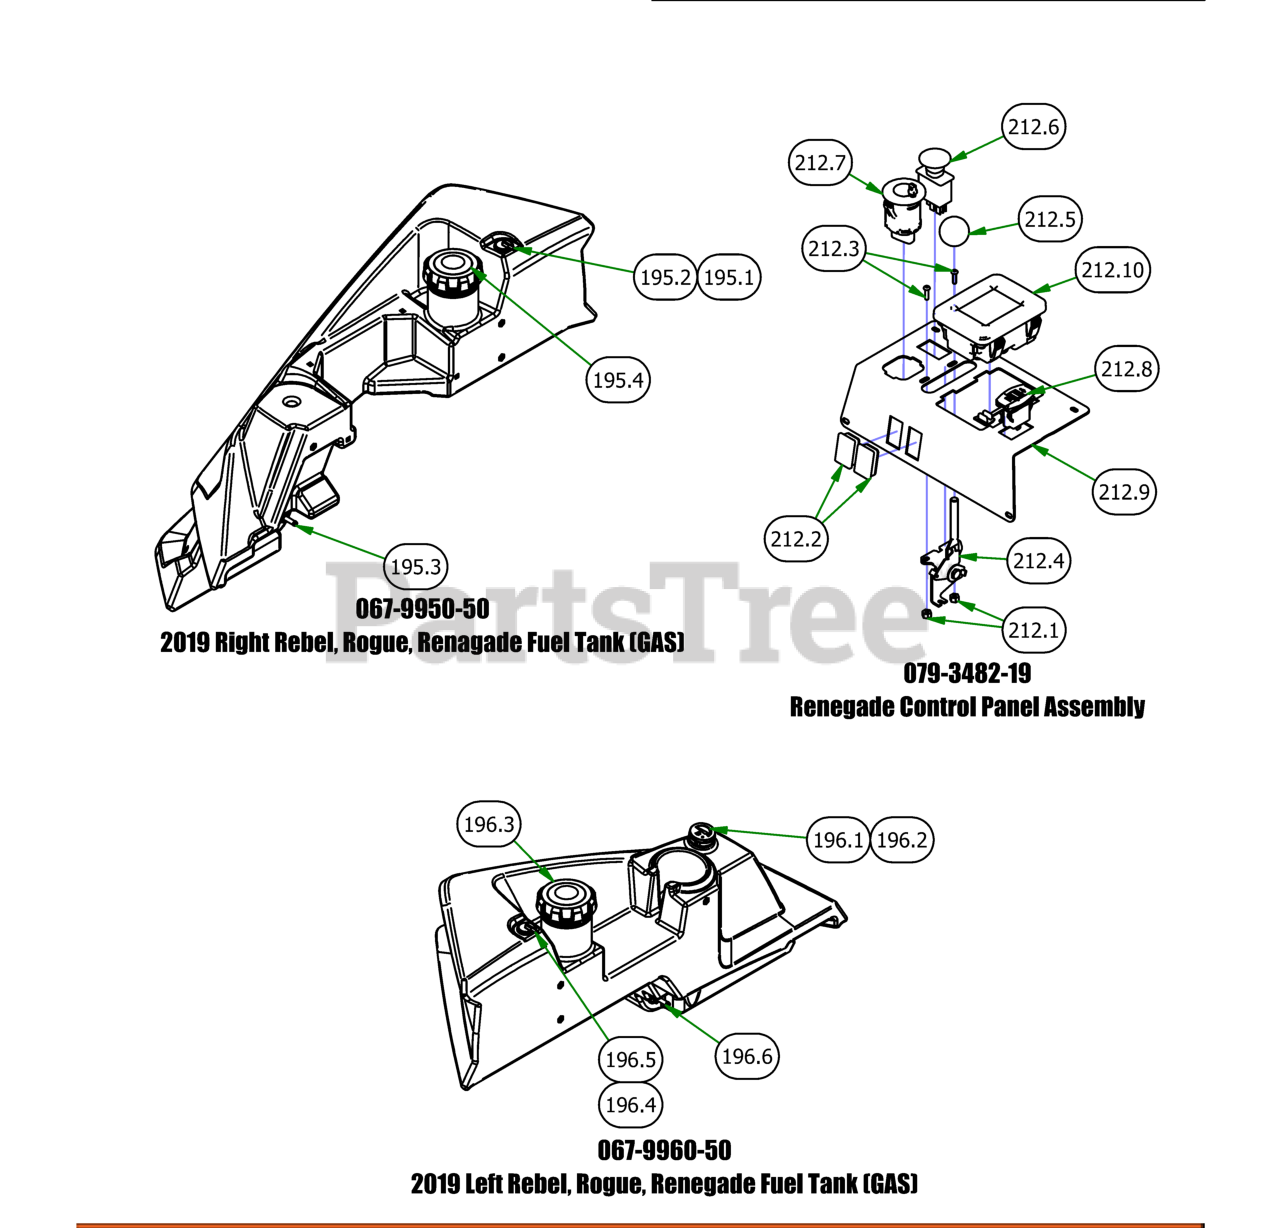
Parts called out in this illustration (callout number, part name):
195.1	Roll Over Valve Grommet
195.2	Rollover Valve
195.3	Fuel Pick-up
196.1	Fuel Gauge with Grommet
196.2	Fuel Gauge Grommet
196.4	Roll Over Valve Grommet
196.5	Rollover Valve
196.6	Fuel Pick-up
212.1	10-24 Nylon Insert Locknut
212.2	Light Plug
212.3	10-24 X 5/8 BS Button Head Bolt
212.4	Universal Throttle
212.5	Throttle Knob
212.6	PTO Switch
212.7	2019 Push to Start Switch w/fob
212.9	2019 Outlaw Digital Control Panel
212.10	2019 LED Display
